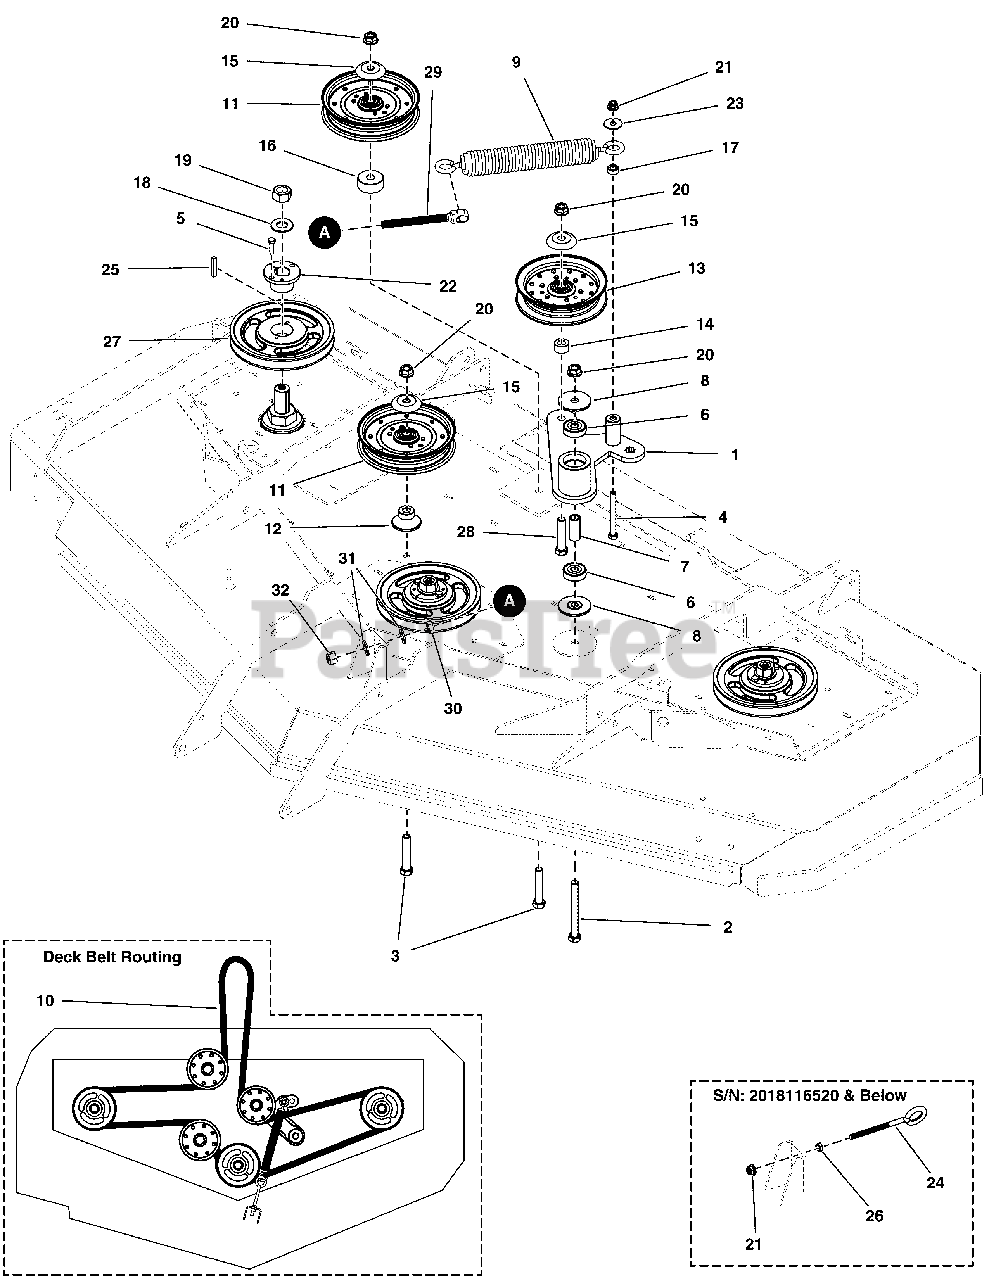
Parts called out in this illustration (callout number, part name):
1	WELD, IDLER ARM, CUTTER DECKS - BLK
2	BOLT, 1/2-13 X 4-1/2" GD5 YZ
3	BOLT, 1/2-13 X 2-3/4 GD5 CZ
4	BOLT, 3/8-16 X 3-1/2" GD5 CZ
5	BOLT, 1/4-20 X 2-1/4 GD5 CZ
6	BEARING, 6203-1/2", SEALED
7	SPACER, .510 X .750 X 1.749, CZ
8	SPACER, IDLER ARM, 1/2 X 2.25
9	SPRING, EXT, 1.5ODX12.25X.234WIRE BLK
10	BELT, SPB/XPB 193.9" EL, LRG ARAMID, 2T
12	IDLER MOUNT
14	SPACER, .52 X 1.00 X .56, PM, CZ
15	SHIELD, PULLEY BEARING, CZ
16	SPACER, .51 x 1.75 x .75
17	SPACER, .39 X .75 X .38, PM, CZ
18	WASHER, 3/4 BELLEVILLE CL/ZC
19	NUT, 3/4-16 Hex
20	NUT, Hex Flange, Nylock, 1/2-13
21	NUT, 3/8 - 16 HEX NYLOCK FLANGE
22	BUSHING, Tapered Hub
23	WASHER, 3/8" Fender
24	EYE BOLT, 3/8-16 X 6, 3THRD, 1EYE, CZ
25	KEY 1/4 SQ X 1 1/2 LONG
26	NUT, 3/8-16 HEX JAM
27	PULLEY, SPINDLE, BH 72
28	BOLT, 1/2-13 X 2-1/2" GD5 CZ
29	SPRING PULLER, 1/2-20, 5.00
30	NUT, 1/2-20 Hex Jam
31	WASHER, 1/2 SAE
32	NUT, 3/8 - 16 HEX NYLOCK FLANGE
